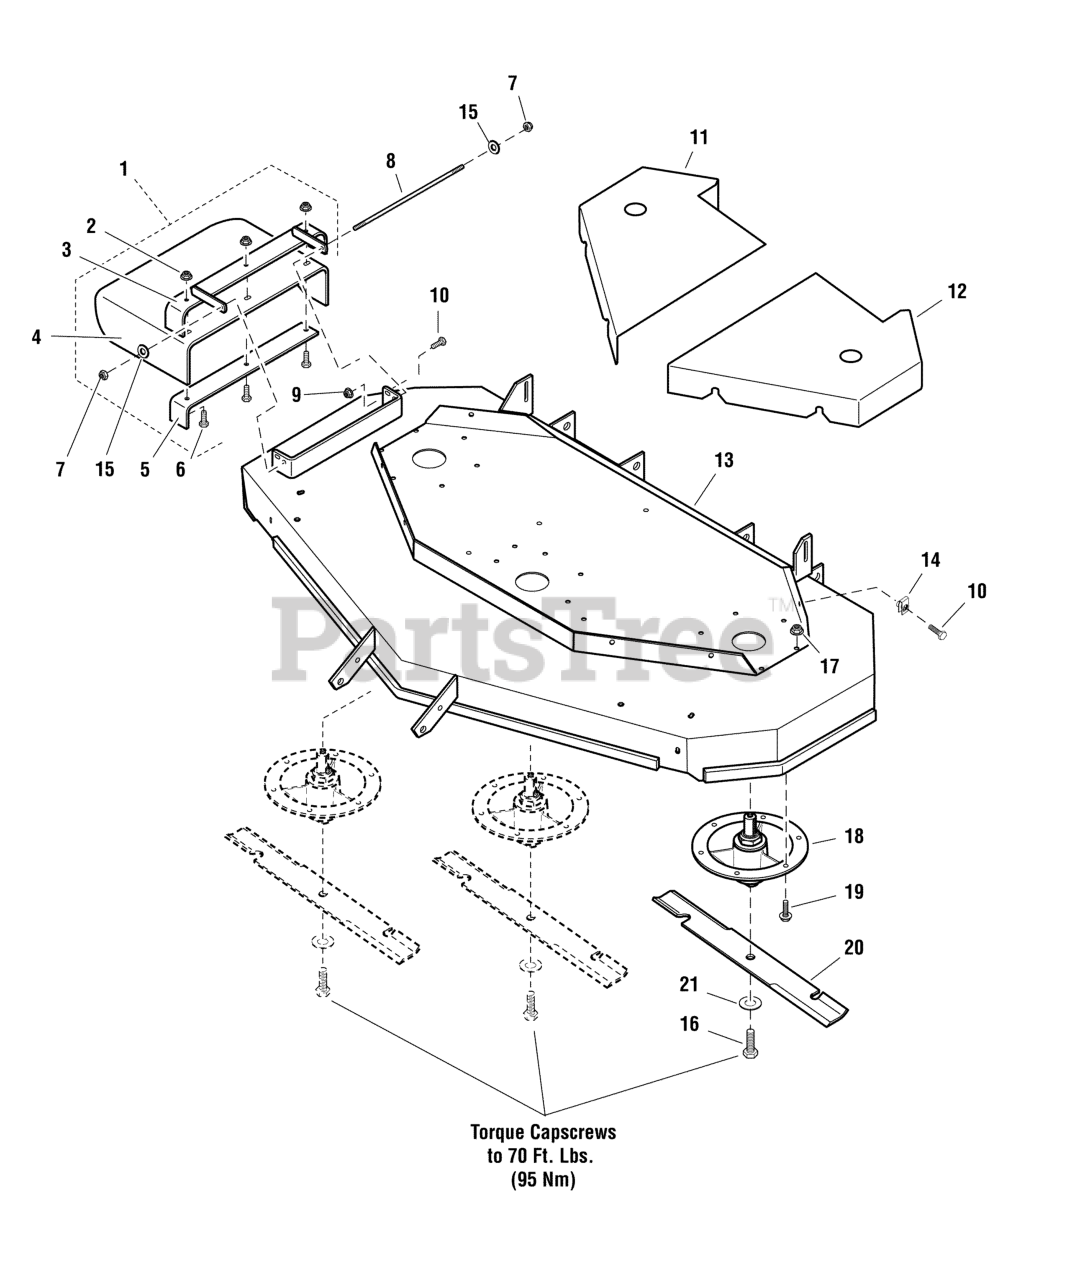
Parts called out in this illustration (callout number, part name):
1	PURCHASE INDIVIDUAL REPLACEMENT PARTS
2	NUT, 3/8-16 HEX NYLOCK FLANGE
3	WELD, FRAME, CHUTE, 61 / 72 - RED
4	CHUTE, DISCHARGE, RUBBER, 61/72, BENT
5	SUPPORT, DISCHARGE CHUTE - BLK
6	BOLT, 3/8-16 X 1-1/4" GD5 CZ
7	NUT, 5/16-24 HEX NYLON LOCK
8	ROD MOUNT, CHUTE
9	NUT, 5/16-18 HEX NYLOCK FLANGE
10	SCREW, 5/16-18x0.750, GR5, WHIZ-LOCK, ZC
11	GUARD 72" - RH - RED
12	GUARD 72" - LH - RED
13	DECK SHELL W/DECALS
14	BODY CLIP, 5/16-18-7GA MATERIAL
15	WASHER, 5/16" GR.9 FLAT
16	BOLT, 5/8-11 X 1-3/4 GD8
17	NUT, 3/8-16 HEX NYLOCK FLANGE
18	SPINDLE ASSEMBLY
19	BOLT, 3/8-16 X 1-1/4", FLANGE
20	BLADE, 25" (SET OF THREE)
21	WASHER, 5/8" GRADE 8, YZ
